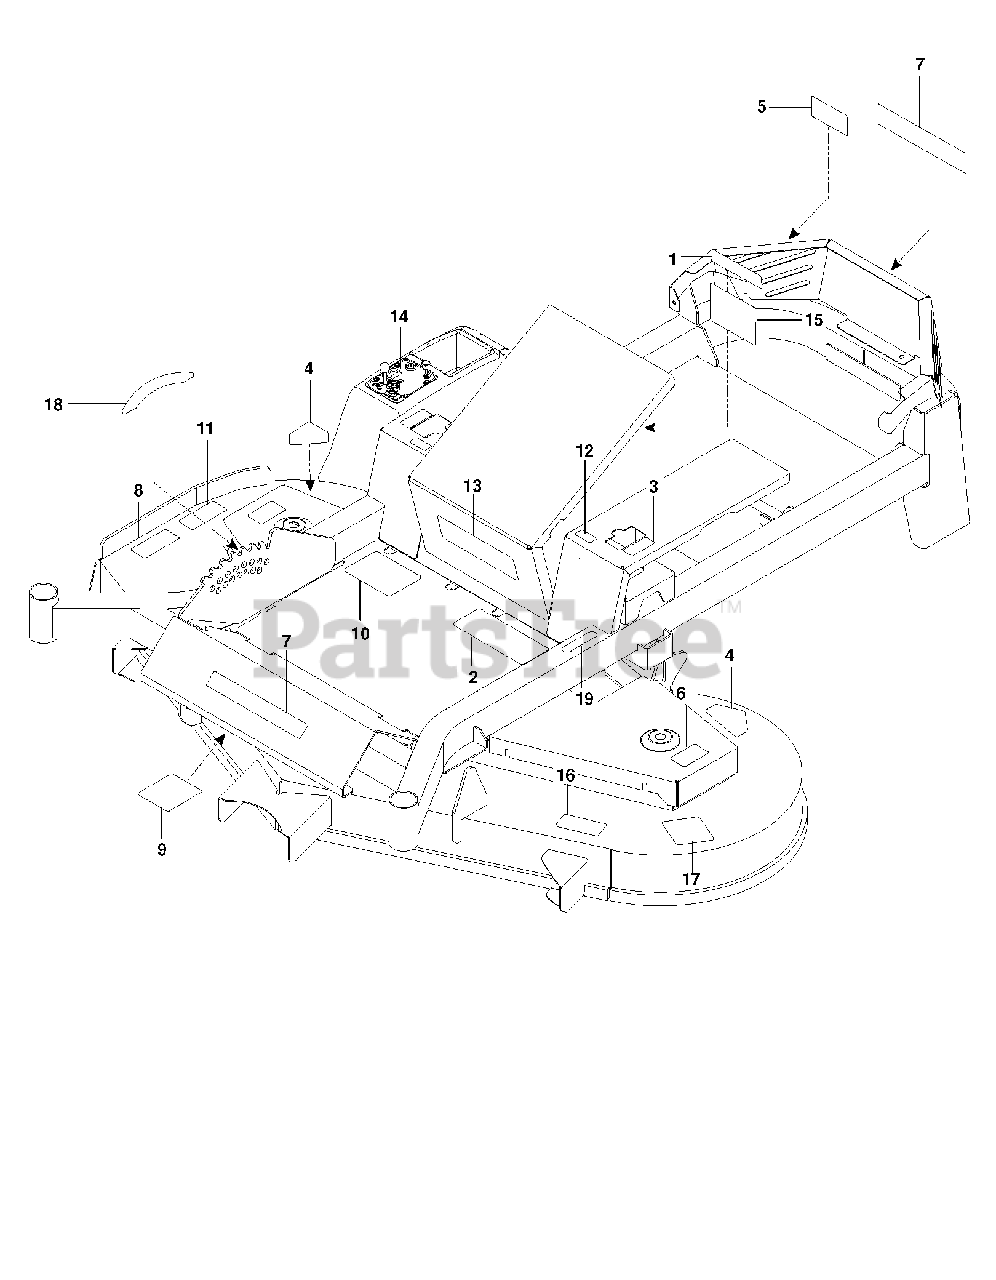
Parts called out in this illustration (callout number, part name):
2	DECAL, WARNING
3	DECAL, MOTION CONTROL
4	DECAL, CPSC
5	DECAL, BELT DRIVE
8	DECAL, EURO SEVERING
9	DECAL, BELT ROUTING
10	DECAL, WARNING
12	DECAL, TRACKING
13	DECAL, RAM ULTRA
15	DECAL, SERVICE
16	DECAL, TRI-FORCE
18	DECAL, HEIGHT ADJUSTMENT
19	DECAL, PARK BRAKE
